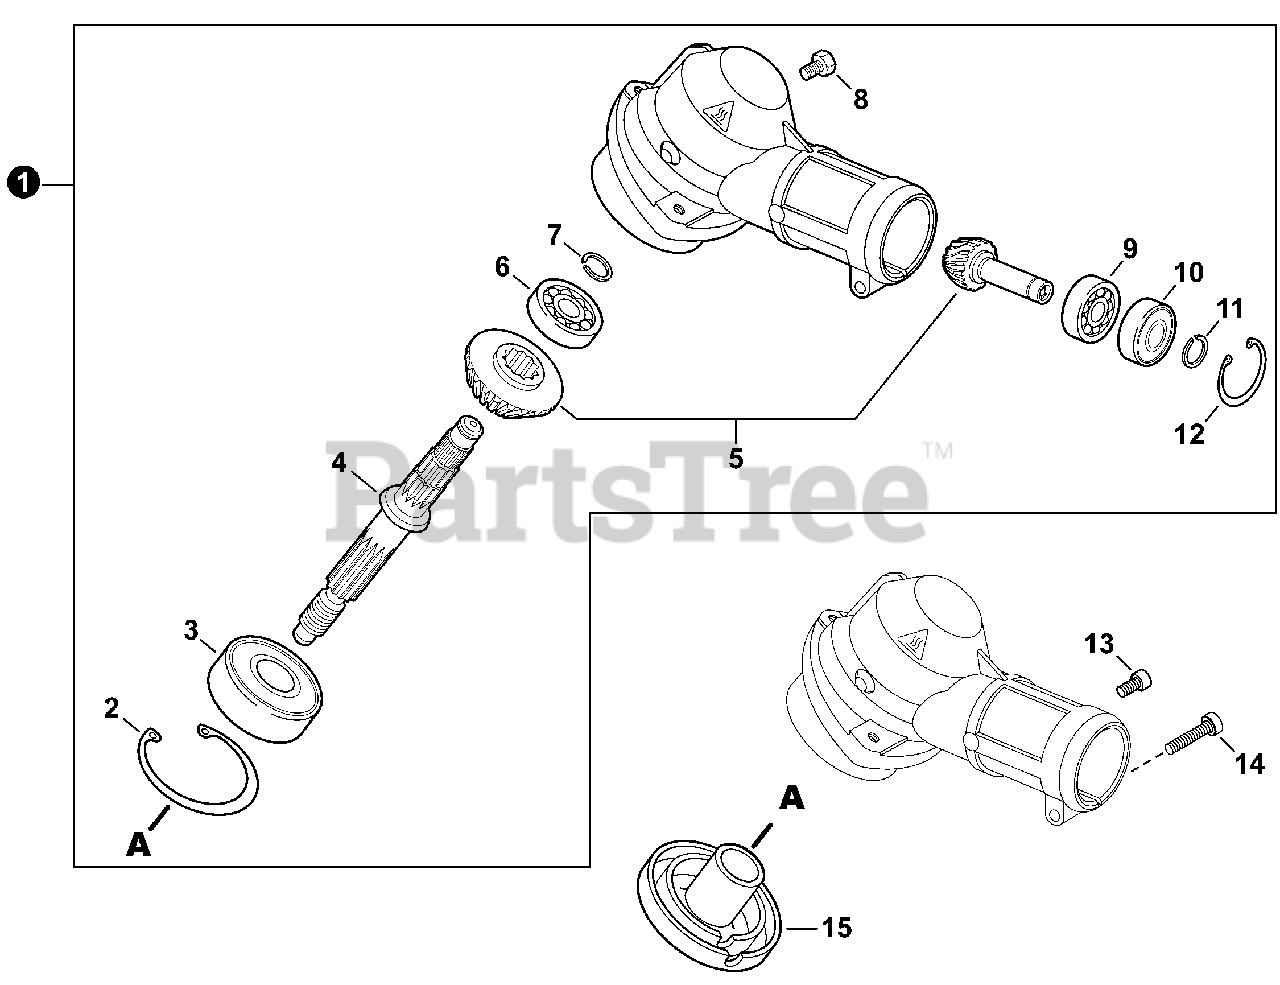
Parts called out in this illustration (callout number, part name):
1	GEAR CASE ASSY
2	RING, SNAP Ø42
3	BEARING, BALL 6302
4	SHAFT, GEAR
5	GEAR SET
6	BEARING, BALL 629
7	RING, SNAP Ø12
8	BOLT M8×8
9	BEARING, BALL 6900
10	BEARING, BALL 6900Z
11	RING, SNAP Ø10
12	RING, SNAP Ø22
13	BOLT, TORX 5×12
14	BOLT, TORX 5×25
15	PLATE, ADAPTOR - UPPER
